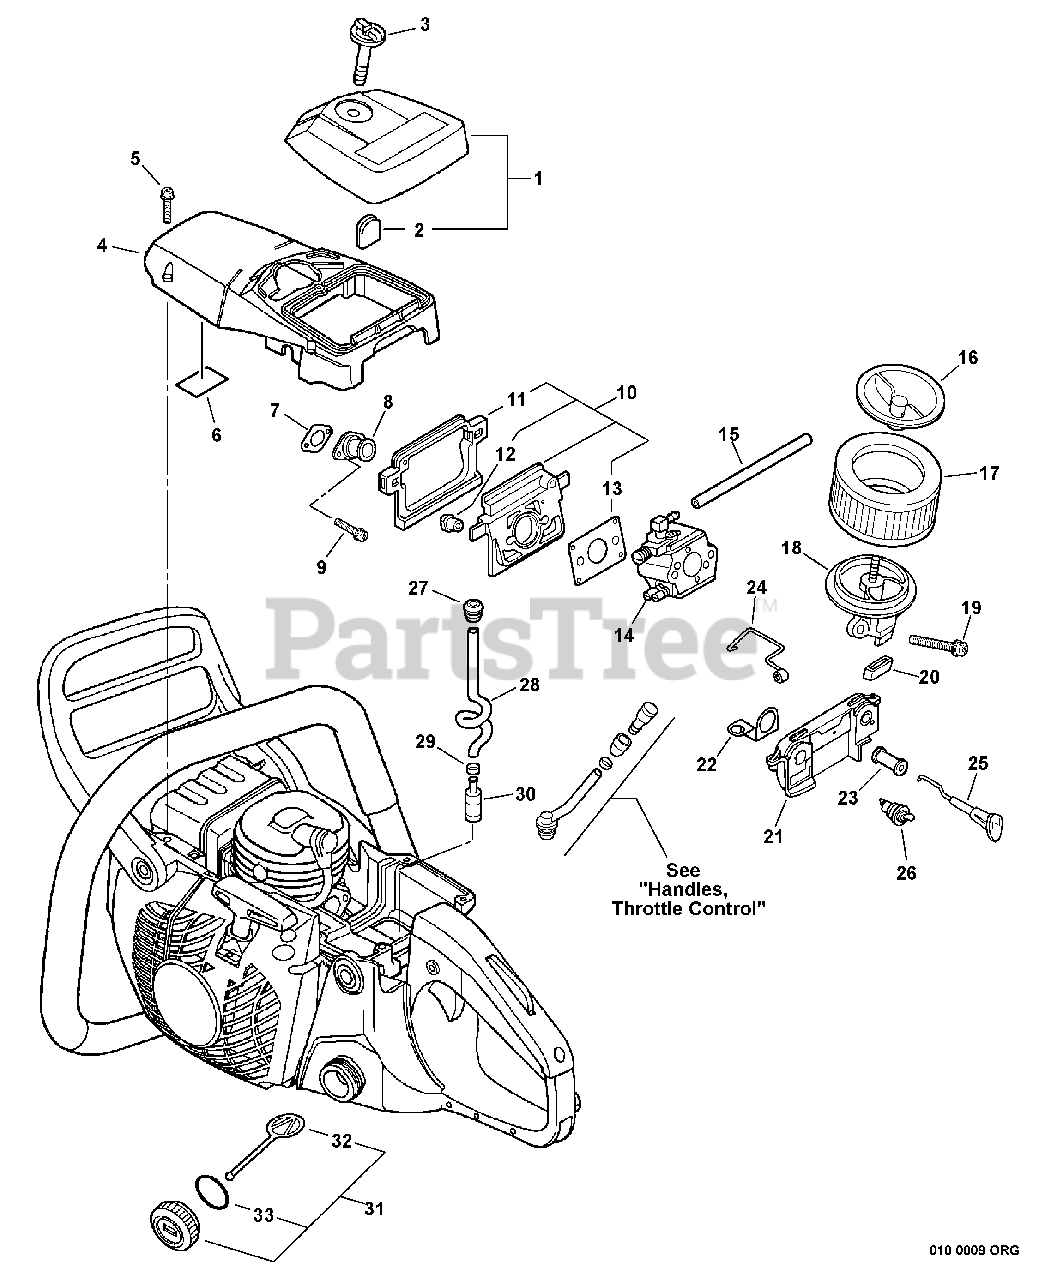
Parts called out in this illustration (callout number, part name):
1	AIR FILTER COVER ASSY - BLACK
3	THUMBSCREW
4	COVER, ENGINE
5	SCREW - 5
6	DEFLECTOR, HEAT
7	GASKET, INTAKE
8	ADAPTOR, INTAKE
9	SCREW - 5X12
10	INSULATOR KIT
11	CUSHION
13	GASKET, INTAKE
14	CARBURETOR
15	PIPE - IMPULSE
16	COVER, AIR FILTER
17	FILTER, AIR
18	ADAPTOR, INTAKE
19	SCREW - 5X50
21	BRACKET, SWITCH
22	TERMINAL - GROUND
23	GROMMET
24	ROD, THROTTLE
25	ROD, CHOKE
26	IGNITION SWITCH ASSY
28	PIPE, FUEL - SPIRAL
29	CLIP - 6.5
30	FILTER, FUEL
31	CAP ASSY - BLACK
32	CONNECTOR, CAP
33	O-RING - 22
